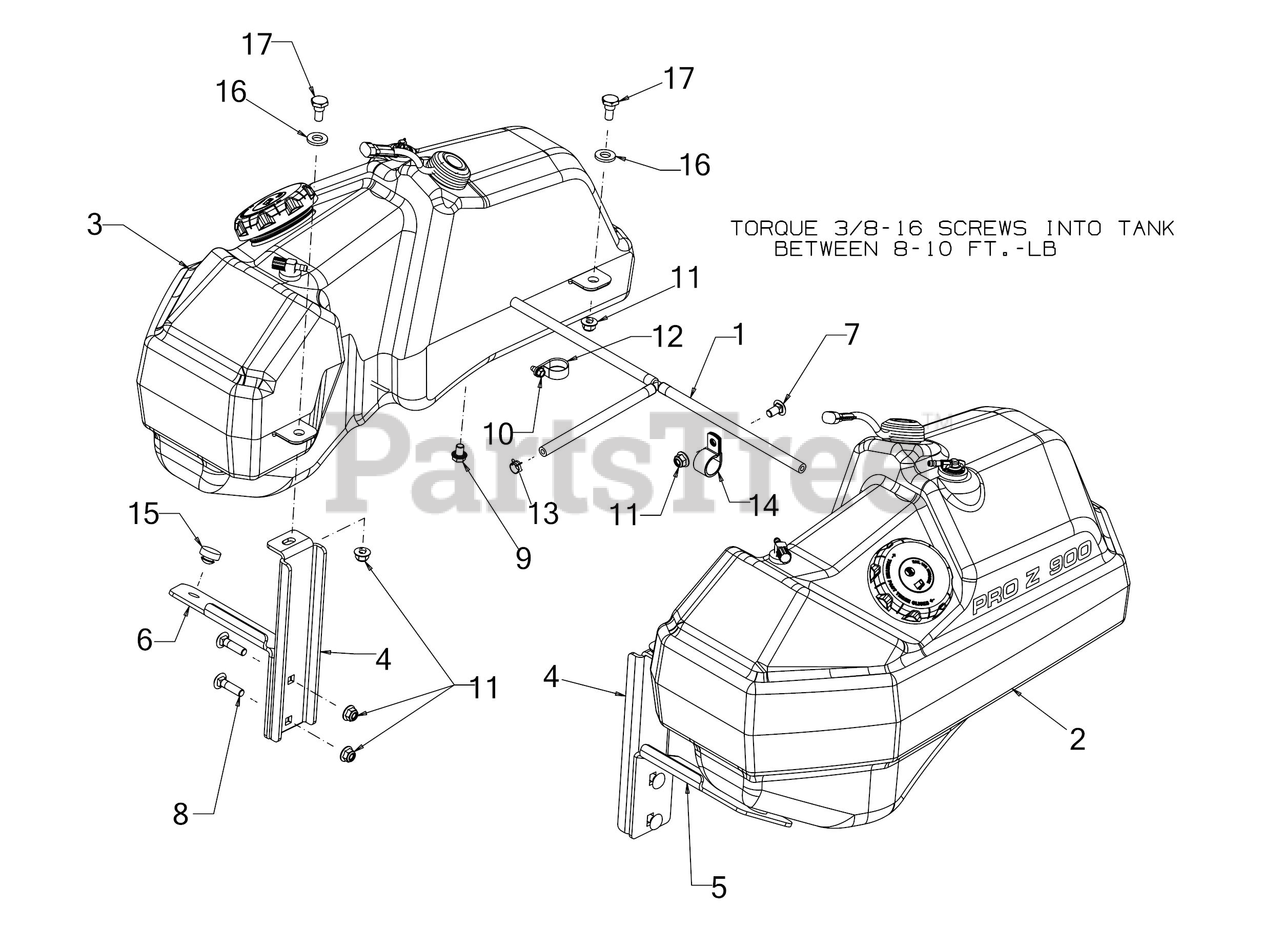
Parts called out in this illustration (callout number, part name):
1	FUEL LINE ASSEMBLY
2	FUEL TANK ASSEMBLY (RH) 7.25 GAL ELC
3	FUEL TANK ASSEMBLY (LH) 7.25 GAL ELC
7	CARRIAGE BOLT 3/8-16 x .750 GR5
8	CARRIAGE BOLT 3/8-16 x 1.50
9	SCREW 3/8-16 x .500 GR5
10	SCREW 1/4-20 X.500
12	DRAIN HOSE CLAMP
14	HOSE CLAMP 1.0"
15	RUBBER BUMPER 1.000 x .313
16	FLAT WASHER .510 x 1.000 x .125
17	SHOULDER SCREW .498 DIA x .340
